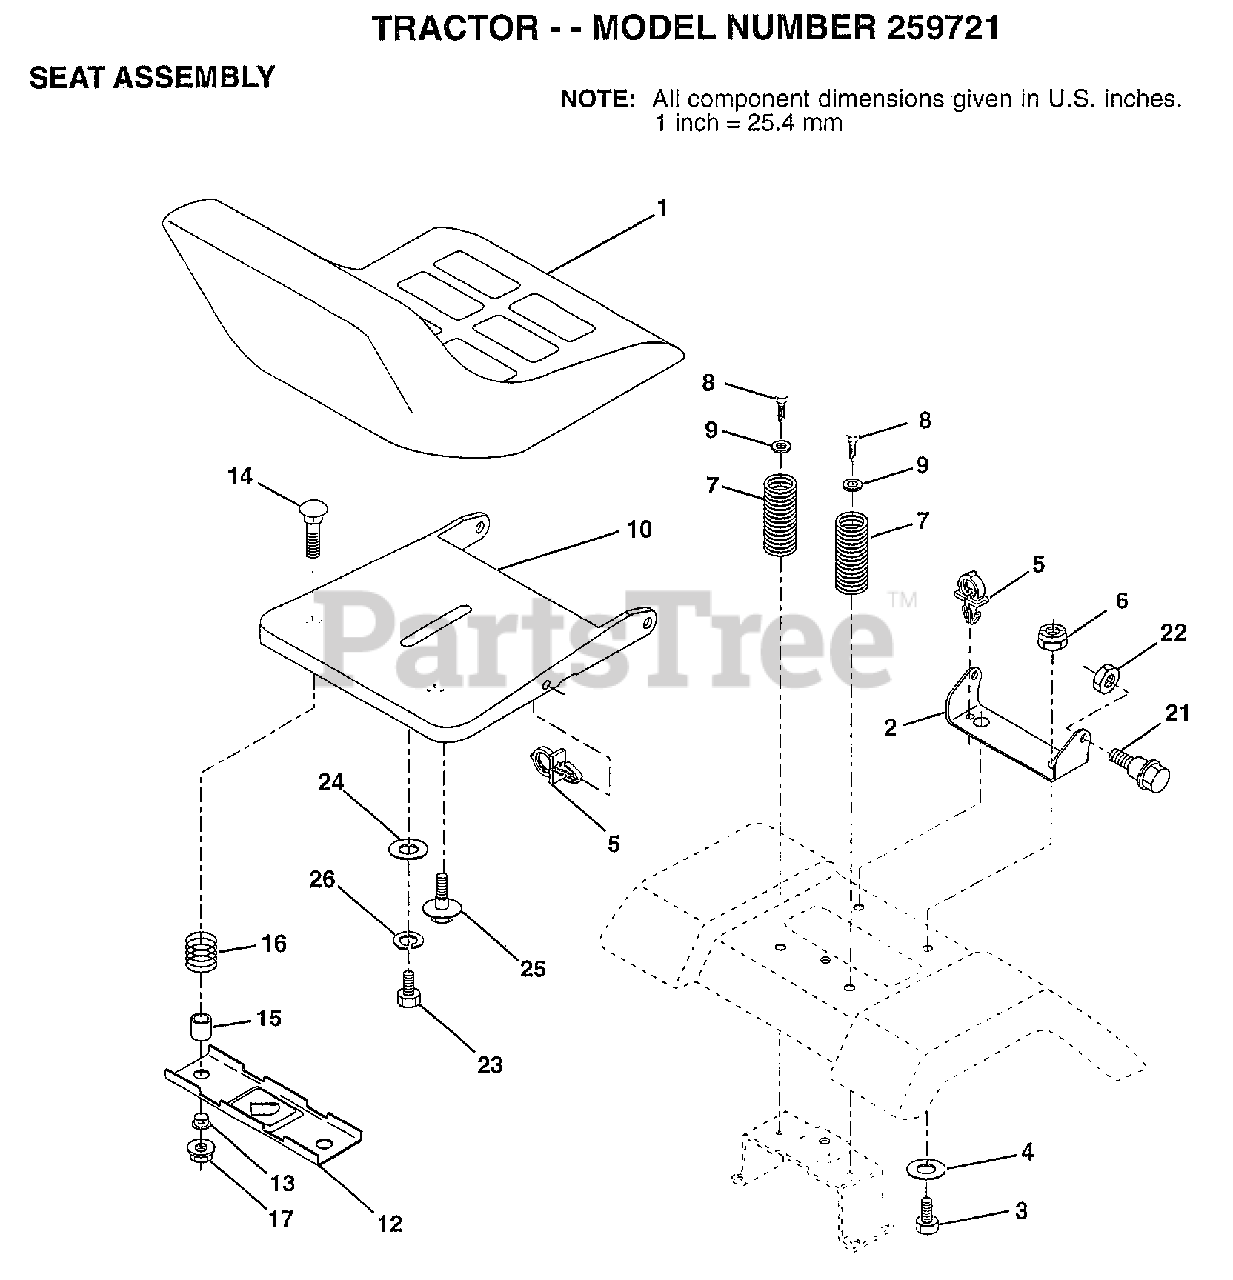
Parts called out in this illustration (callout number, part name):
2	BRACKET PVT SEAT
3	BOLT
4	WASHER PM
5	CLIP.PUSH-IN.HING
6	NUT
7	SPRING COMPRESSIO
8	SCREW GTV
9	WASHER
10	PAN-SEAT
12	BRKT SWITCH
13	BUSHING
14	BOLT-RD HD SQ NK
15	SPLIT SPACER
16	SPRING
21	"BOLT,SHOULDER"
22	NUT
23	BOLT
24	WASHER
25	"BOLT,SHOULDER"
26	LOCKWASHER
